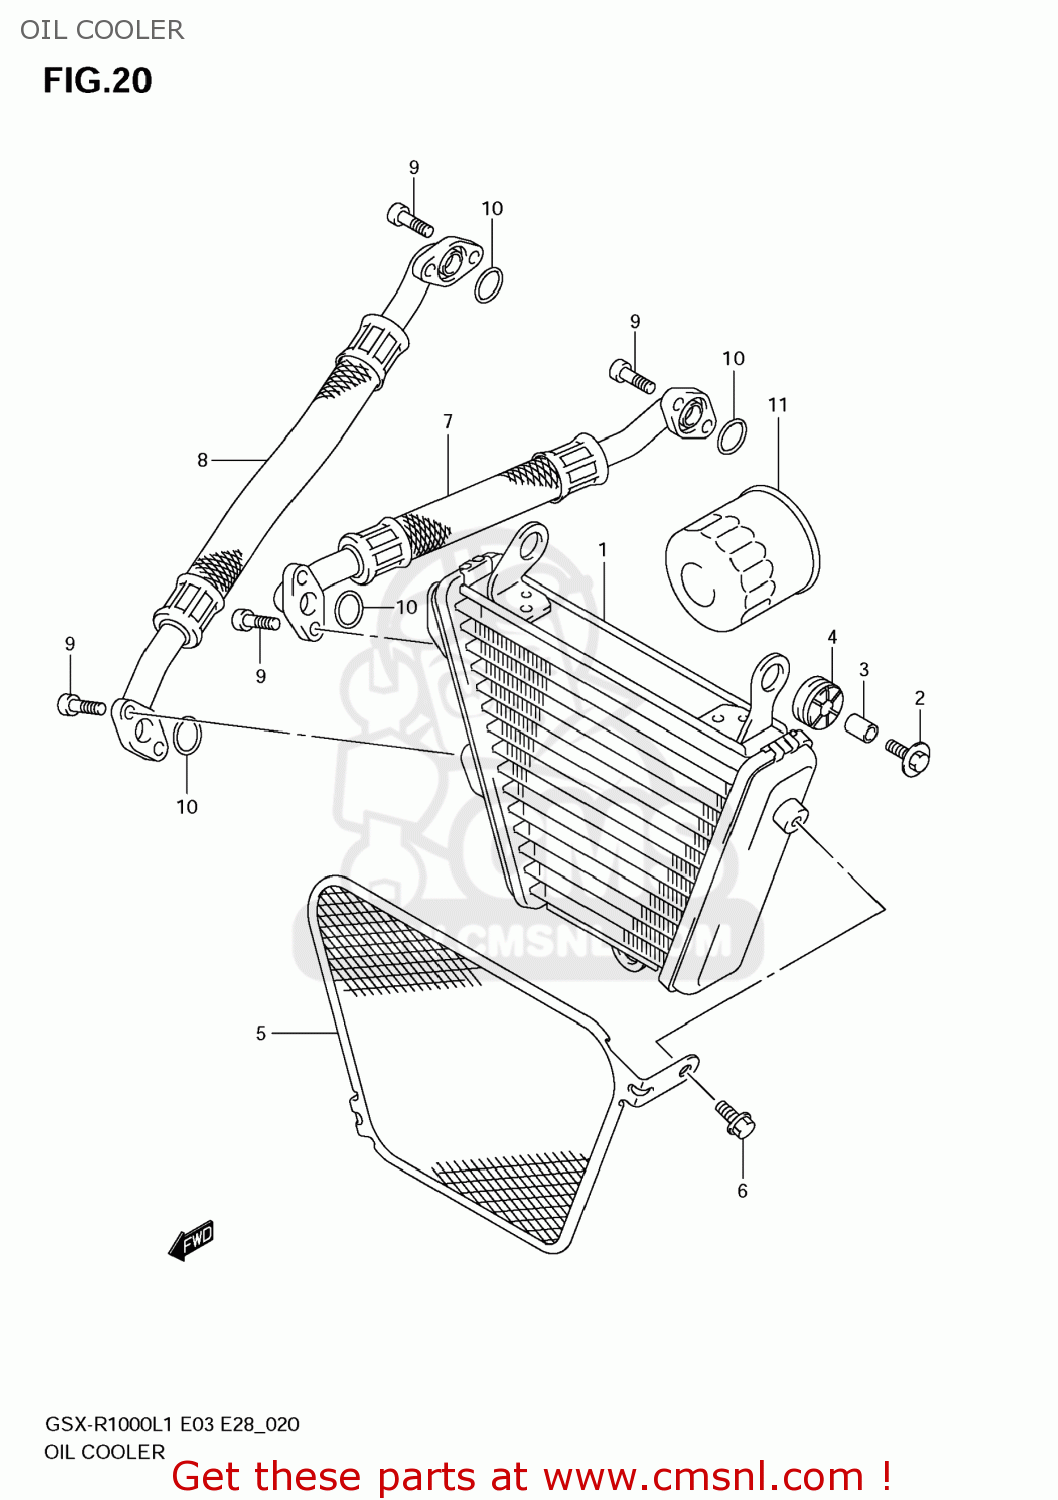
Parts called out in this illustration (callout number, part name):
1	COOLER ASSY,OIL
2	BOLT(6X25)
3	SPACER(6.5X10X12)
4	CUSHION
5	GUARD,OIL COOLER
6	BOLT
7	HOSE,OIL COOLER INLET
8	HOSE,OIL COOLER OUTLETLET
9	BOLT(6X16)
10	O RING(D:2.4,ID:16)
11	FILTER ASSY,ENGINE OIL
